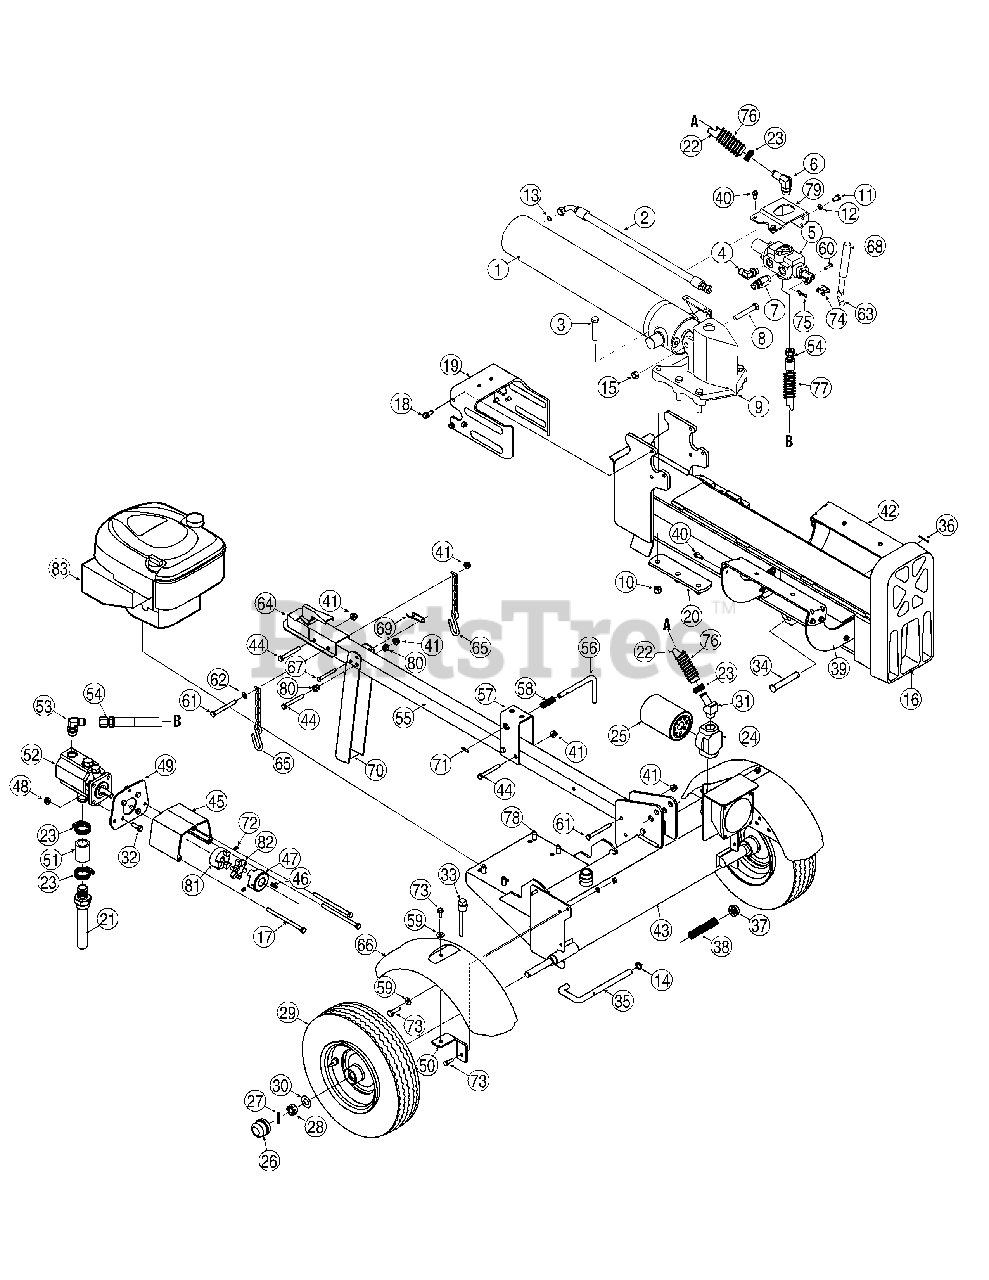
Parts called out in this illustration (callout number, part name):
1	Hydraulic Cylinder
2	Hydraulic Tube
3	Hex Cap Screw, 1/2-20 x 2.75
4	90 Degree Solid Adapter
5	Control Valve
6	Return Elbow
7	Nipple Pipe, 1/2-14
8	Hex Cap Screw, 1/2-13 x 3.25
9	Wedge Assembly
10	Hex Lock Nut, 1/2-20
11	Hex Cap Screw, 3/8-16 x .75
12	Lock Washer, 3/8
13	O-Ring, .489 x 070
14	Flat Washer, .635 x.93 x.06
15	Hex Lock Nut, 1/2-13
16	Beam Assembly
17	Hex Screw, 5/16-18 x 3.25
18	Self Tapping Screw, 3/8-16 x 1.0
20	Back Plate
21	Inlet Filter
22	Return Hose, 3/4 x 44
23	Hose Clamp, 5/8
24	Filter Housing
25	Oil Filter
26	Hub Cap
27	Cotter Pin
28	Slotted Nut, 3/4-16
29	Complete Wheel Assembly
30	Flat Washer, .760 x.500
31	Hydraulic Fitting
32	Hex Screw, 5/16-18 x 1.00
33	Vented Dipstick
34	Clevis Pin
35	Lock Rod
36	Cotter Pin
37	Push Cap
38	Compression Spring
39	Log Tray Bracket
40	Hex Washer Screw, 5/16-18 x .750
41	Flange Lock Nut, 3/8-16
44	Hex Bolt, 3/8-16 x 3
45	Coupling Shield
46	Square Key, 3/16" x .75
47	Coupling, .875
48	Flange Lock Nut, 5/16-18
49	Rear Coupling Support Bracket
50	Fender Mounting Bracket
51	Hose
52	Gear Pump
53	45 Degree Elbow Fitting
54	High Pressure Hydraulic Hose
56	Latch Rod
58	Compression Spring
59	Flat Washer
60	Clevis Pin
61	Hex Cap Screw, 3/8-16 x 3.50
62	Flat Washer, .375 x.738 x.063
63	Hydraulic Valve Control
64	Hitch Coupling Assembly
66	Fender
67	Clevis Pin
69	Spring Pin
71	Spiral Pin
72	Set Screws
73	Self-Tapping Screw, 5/16-18 x 1.00
74	Valve Handle Link
75	Cotter Pin, Bow Tie
76	Hose Guard, 44"
77	Hose Guard, 48"
78	Sems Screw, 3/8-16 x 1.00
79	Outer Valve Bracket
80	Plastic Bushing, .380 ID
81	Coupling, .500
82	Spider Bushing
